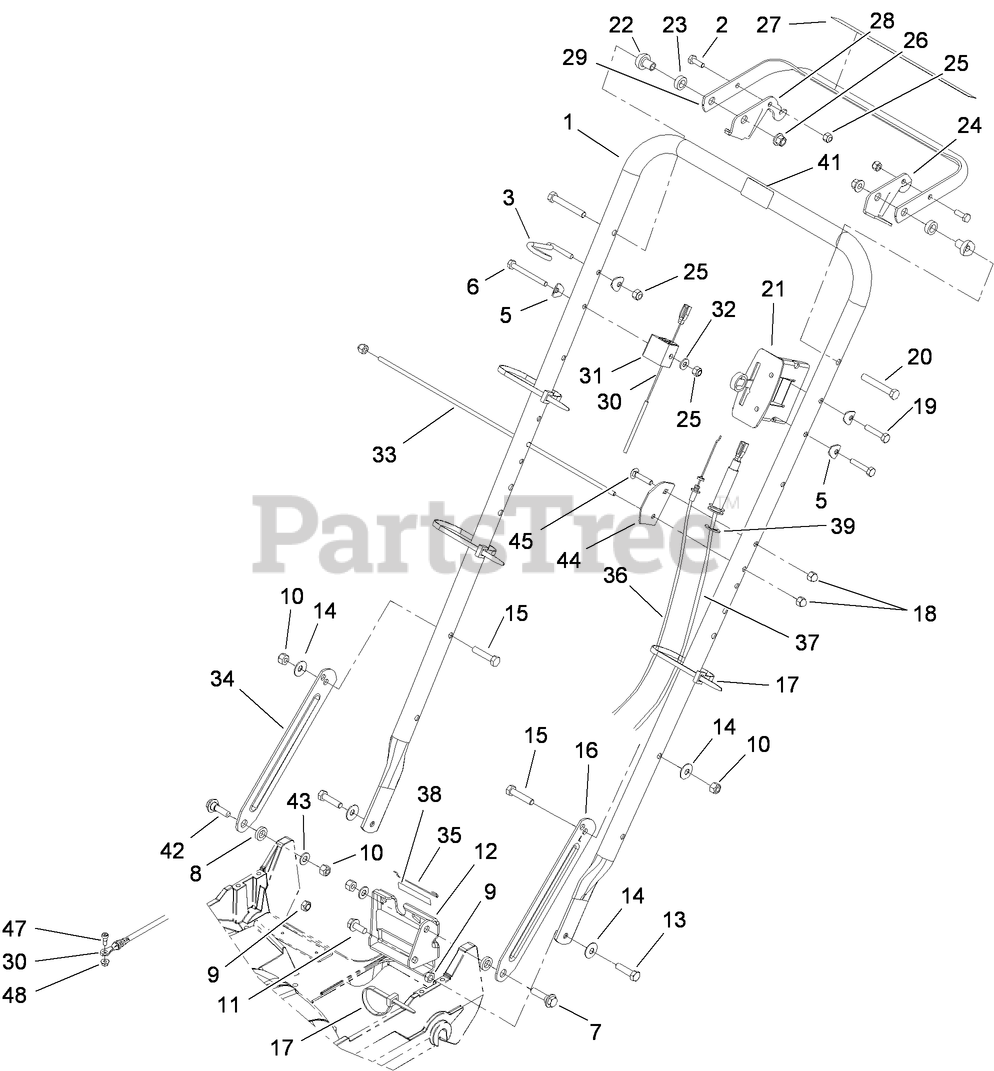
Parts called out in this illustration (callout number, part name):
2	SCREW-HH
3	GUIDE-ROPE
5	WASHER
6	SCREW-HH
7	SCREW-SHOULDER
8	SPACER
9	NUT-LOCK, NI
10	NUT-LOCK, NI
11	SCREW-HWHTF
12	BRACKET-ADJUSTMENT, TRACTION
13	SCREW-HH
14	WASHER-BELLEVILLE
15	SCREW-HH
16	LATCH-HANDLE, LH
17	TIE-CABLE
18	NUT-CAP
19	SCREW-HH
20	SCREW-HH
21	CONTROL-HEAD, THROTTLE
22	SPACER-SUPPORT
23	SPACER-NYLON
24	LEVER-CONTROL
25	NUT-LOCK, NI
26	NUT-LOCK, NI
27	DECAL-TRACTION
28	LEVER-CONTROL
29	BAR-CONTROL
30	CABLE-BRAKE, CONTROL
31	SUPPORT-CABLE
32	WASHER-FLAT
33	ROD-SUPPORT, BAG
34	LATCH-HANDLE, RH
35	RETAINER-CABLE
36	CABLE-TRACTION
37	THROTTLE CABLE ASM
38	DECAL-POSITION, GEAR
39	E-RING
41	DECAL-PROTECTION, EAR
42	SCREW-SHOULDER
43	WASHER-PLAIN
44	PLATE-ALIGNING, BAG
45	SCREW-CARR
47	SCREW-SHOULDER
48	NUT-LOCK, FLANGE
